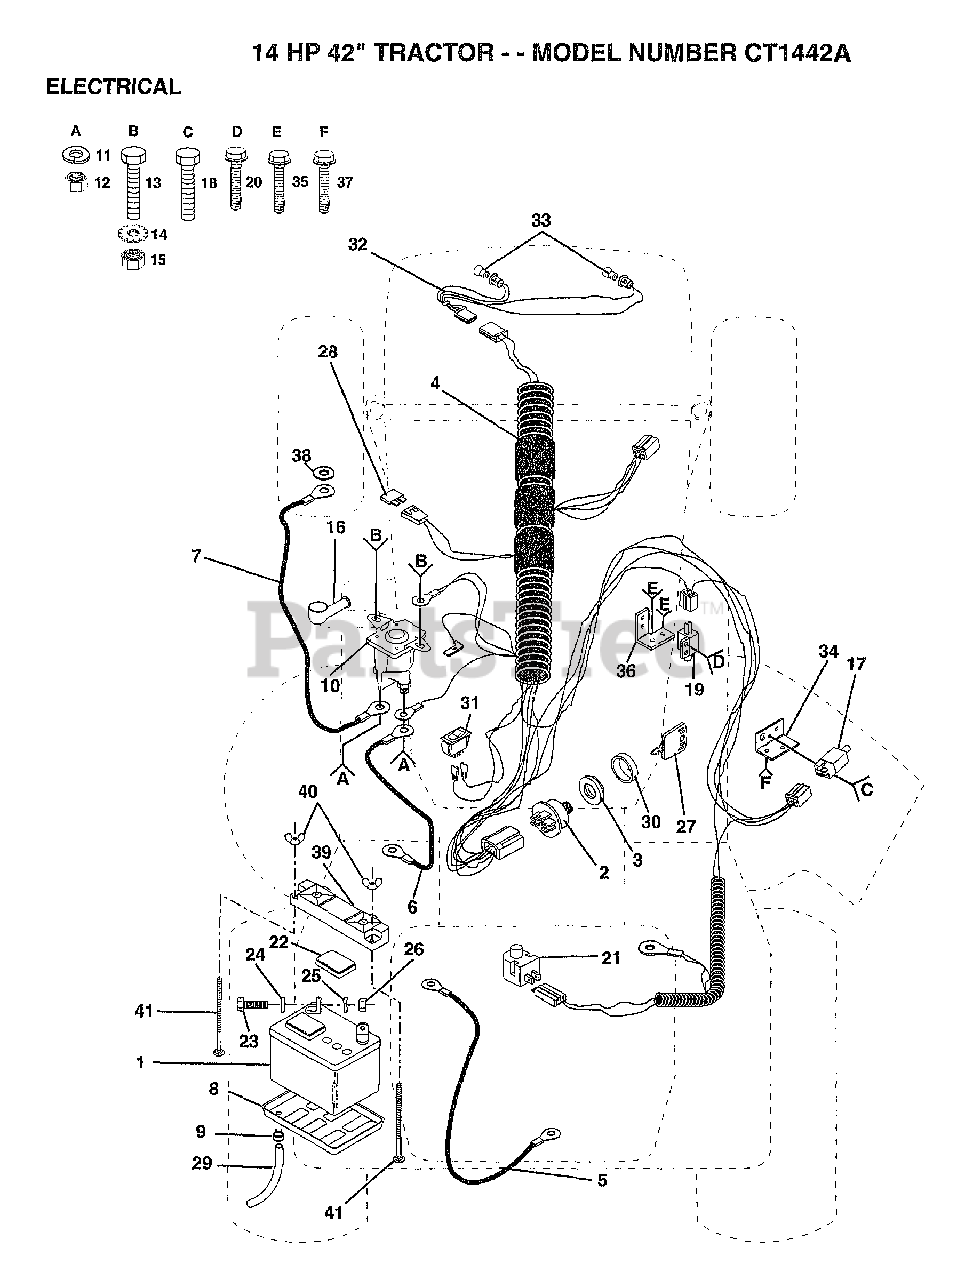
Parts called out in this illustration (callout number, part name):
3	NUT IGNITION
4	HARNESS.IGN
5	CABLE T
7	"CABLE T, BATTERY"
8	"TRAY T, BATTERY"
9	HOSE CLAMP T
12	NUT
13	BOLT
15	NUT
17	SWITCH INTERLOCKT
18	SCREW
19	SWITCH-INTER. GT
20	SCREW
21	SWITCH SEAT
22	"CAP,BATTERY "
23	BOLT LT
24	WASHER
25	LOCKWASHER
27	KEY
28	FUSE HYT
29	"DRAIN TU T, BATT"
31	SWITCH LT
32	"HARNESS,LIGHT SOC"
34	BRACKET LT
35	SCREW
36	SWITCH BRACKET
37	SCREW
38	LOCKWASHER
41	BOLT
